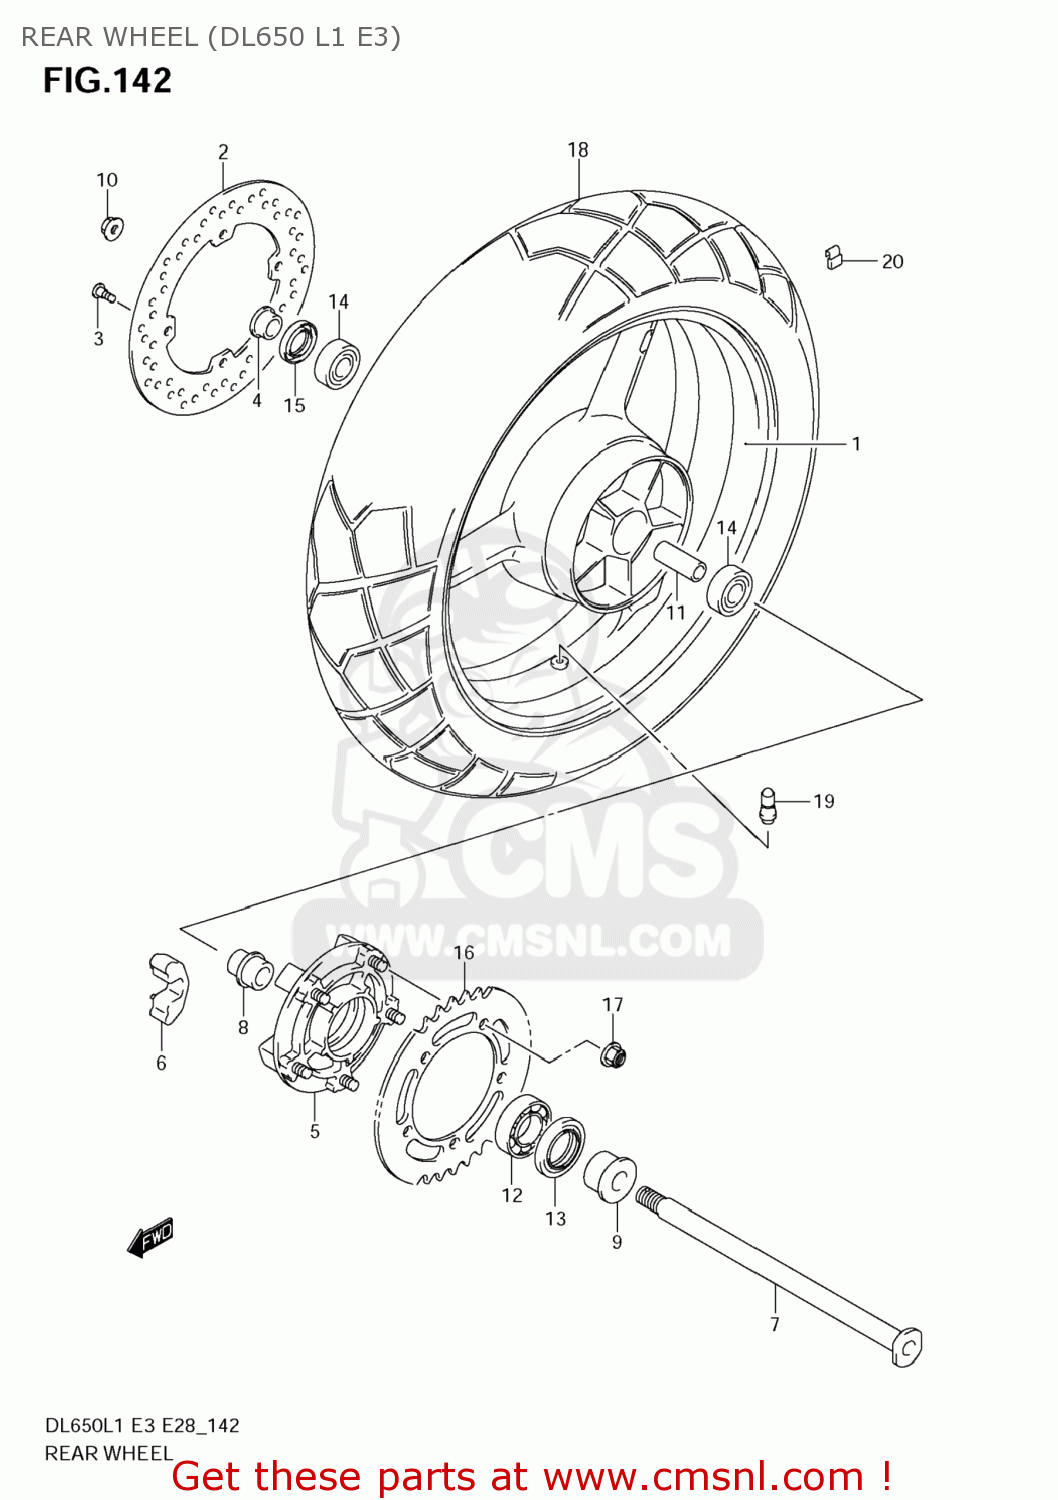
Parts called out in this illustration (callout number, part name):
1	WHEEL,RR(17M/CXMT4.00)
2	DISC,RR BRAKE
3	BOLT(8X21)
4	SPACER,RR AXLE,R
5	DRUM, REAR SPROCKET
6	ABSORBER,RR HUB SHOCK
7	AXLE,RR
8	RETAINER,RR SPROCKET DRUM
9	SPACER,RR AXLE,L
10	NUT
11	SPACER(20.8X27.2X124)
12	BEARING
13	SEAL,OIL(39X65X7)
14	BEARING
15	SEAL,OIL(28X47X7)
16	SPROCKET,RR(47T-525)
17	NUT
18	TIRE,REAR,150/
19	VALVE ASSY,WHEEL RIM(TR412)
20	WEIGHT,WHEEL BALANCE 10G
